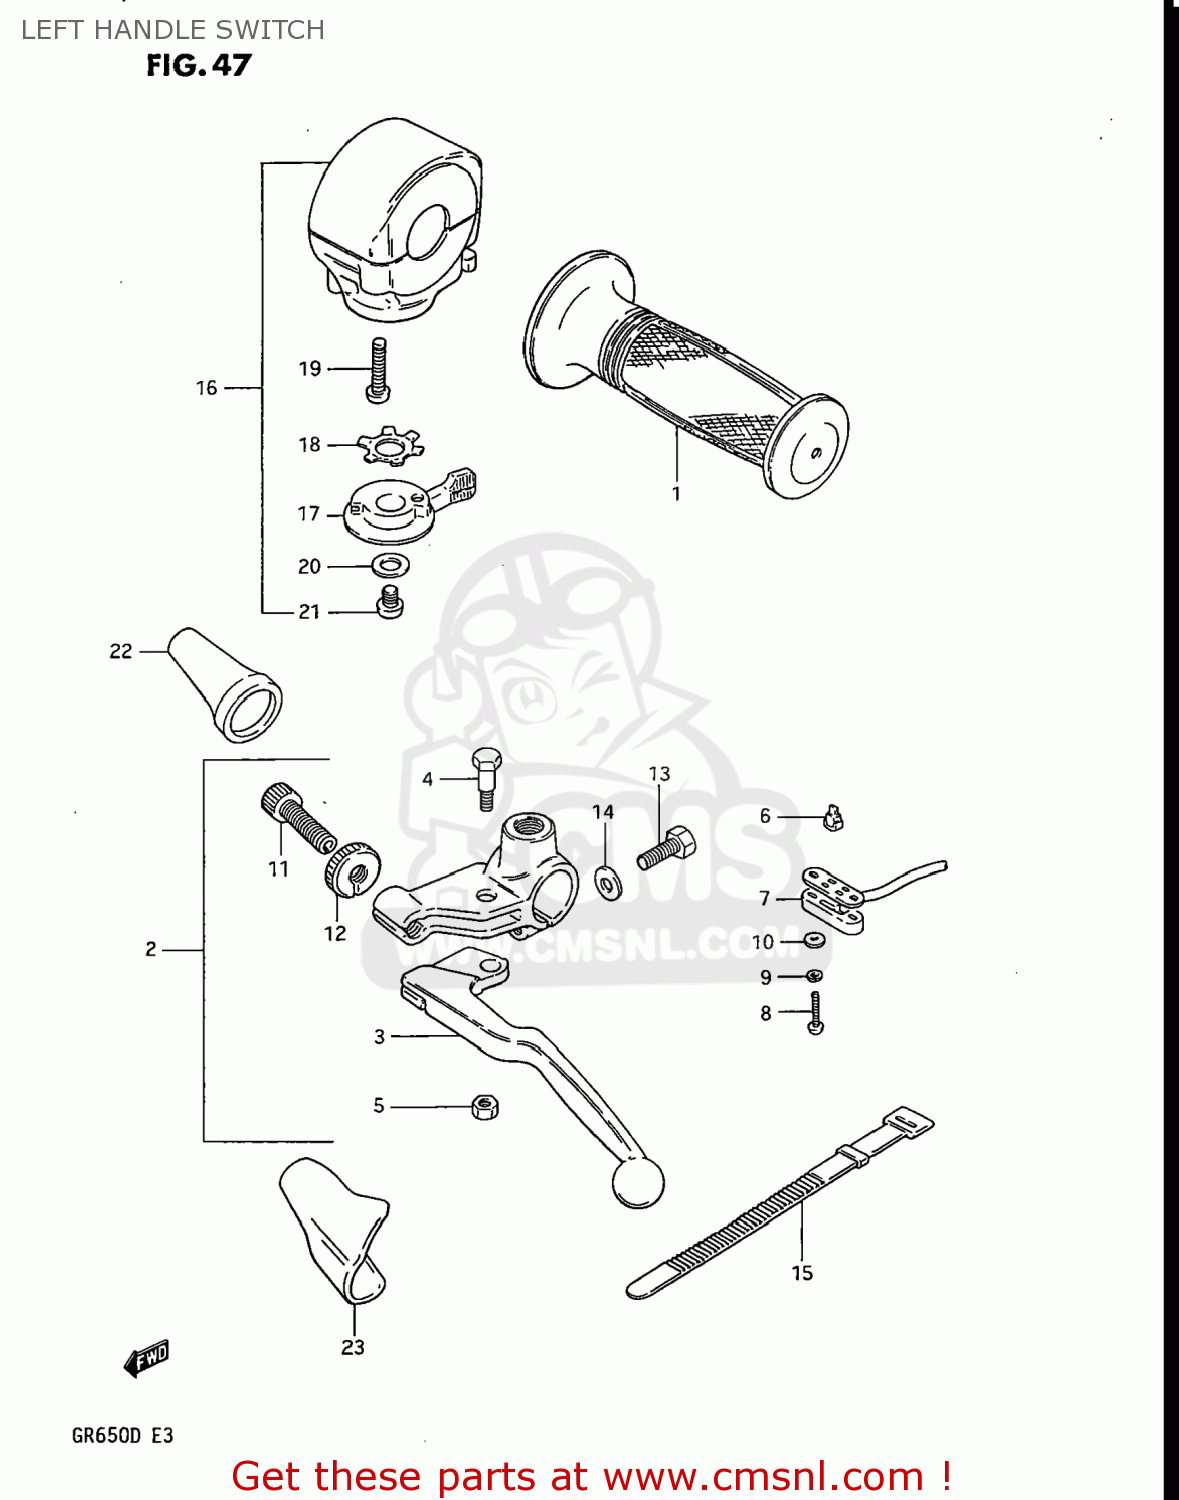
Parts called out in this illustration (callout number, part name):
1	GRIP
2	LEVER ASSY,CLUTCH
3	LEVER,CLUTCH
4	BOLT,LEVER
5	NUT 6MM
6	CONTACT,SWITCH
7	COVER,FR BK TERMINAL BASE
8	SCREW
9	LOCK WASHER
10	WASHER
11	ADJUSTER,CABLE
12	NUT,CABLE ADJUSTER LOCK
13	BOLT,CLUTCH LEVER HOLDER
14	SPACER
15	CLAMP(L:120)
16	SWITCH ASSEMBLY,HANDLE,LEFT
17	LEVER,STARTER
18	WASHER
19	SCREW
20	WASHER 6MM
21	SCREW
22	BOOT,CLUTCH CABLE
23	COVER,CLUTCH LEVER
